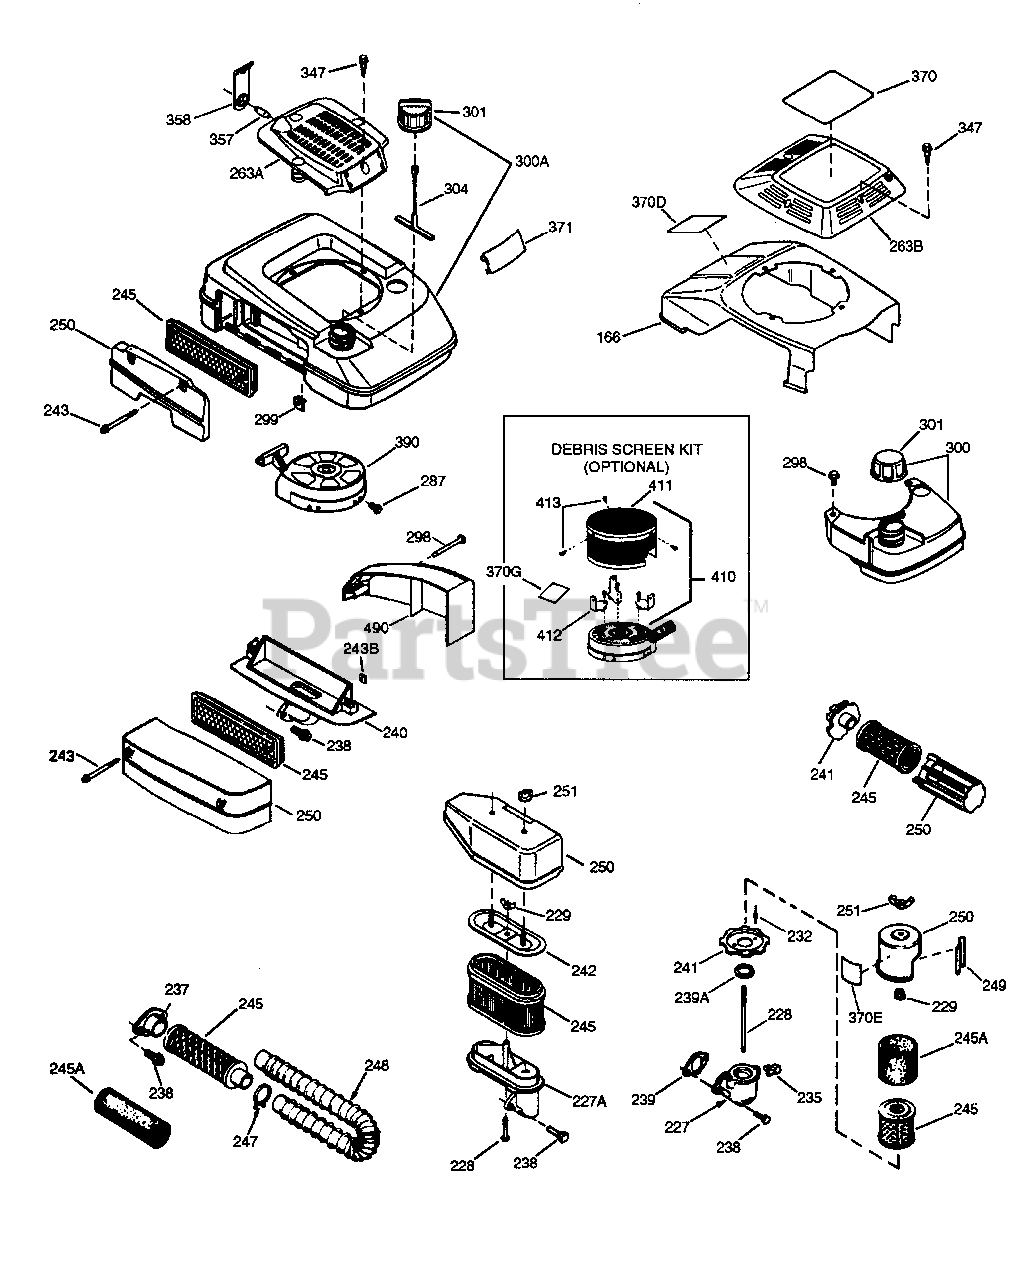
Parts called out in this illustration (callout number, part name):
238	Screw, 10-32 x 43/64"
239	* Air Cleaner Gasket
240	Air Filter Body (Incl. 239 & 243B)
243	Screw, M-5 x 0.8-6g x 2-7/16"
243B	Square Nut, M-5 x 0.8-6H
245	Air Filter (also available in Package d Part #740013B)
250	Air Filter Cover
263A	Starter Grill
287	Screw, 8-32 x 21/64"
298	Screw, 10-32 x 35/64"
300	Fuel Tank (Incl. 292 & 301)
301	Fuel Cap
390	Rewind Starter (NOTE: This engine co uld havbeen built with 590702 starter ).
